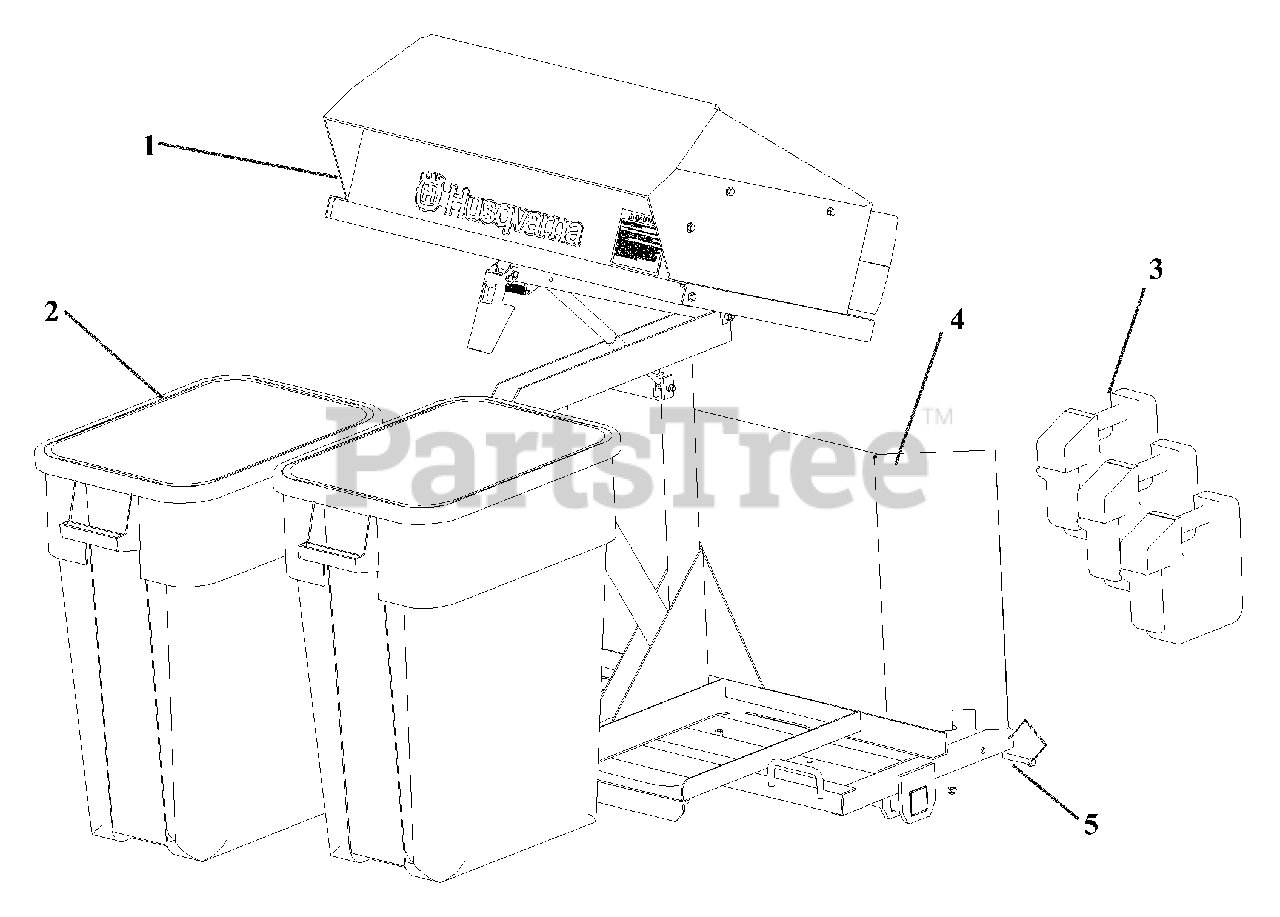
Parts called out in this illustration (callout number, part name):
1	Frame/Top Assembly
2	Container, 30 Gal.
3	Front Weight
4	Heat Shield
5	Pin, Wire Lock
